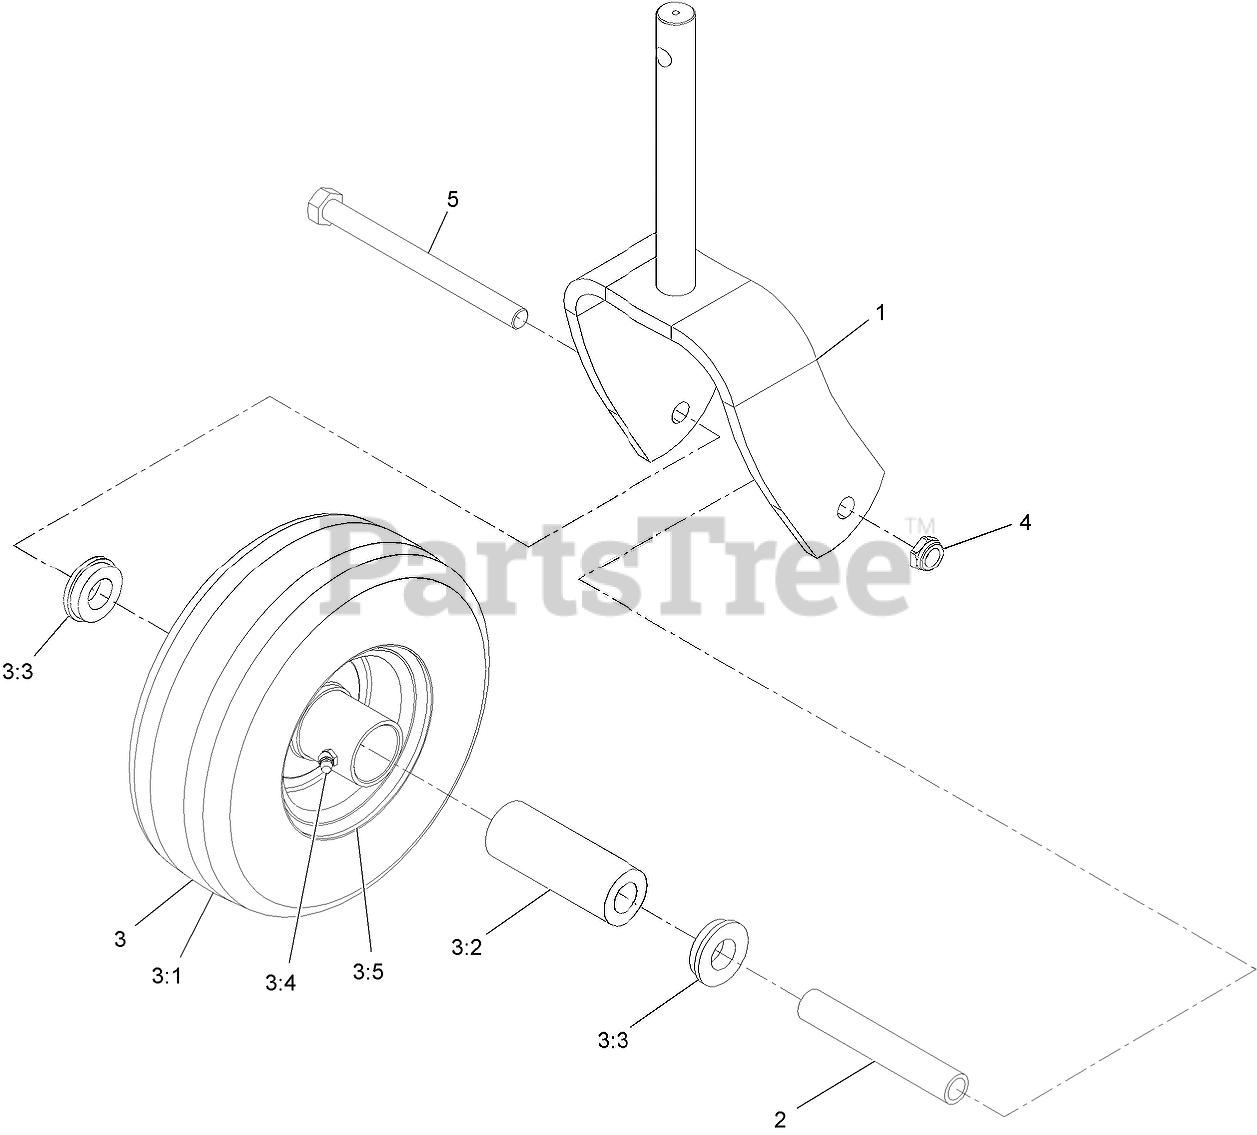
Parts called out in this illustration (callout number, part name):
1	FORK-CASTER
3	WHEEL AND TIRE ASM
3:1	Tire
3:2	BEARING
3:3	BUSHING
3:4	FITTING-GREASE
3:5	Wheel
4	NUT-HEX
5	SCREW-HH
